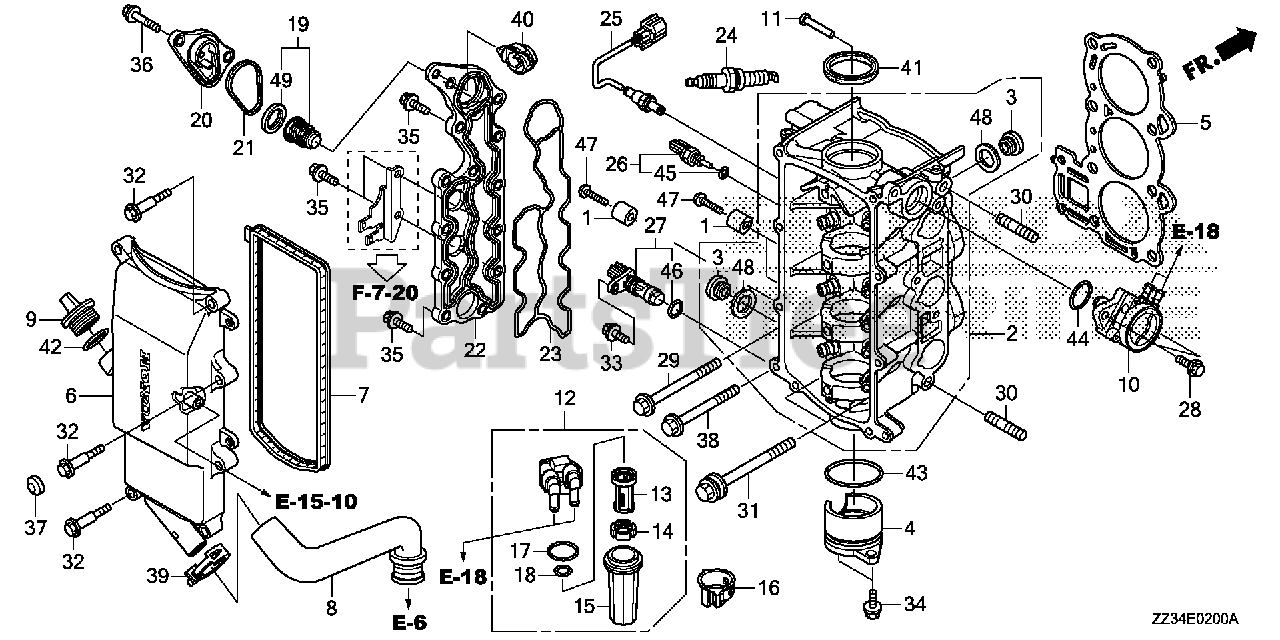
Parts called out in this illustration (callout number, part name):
1	METAL, ANODE
2	CYLINDER HEAD *NH8* (DARK GRAY)
3	BOLT, SEALING (20MM)
4	COVER, CAM THRUST
5	GASKET, CYLINDER HEAD
6	COVER, CYLINDER HEAD
7	GASKET, HEAD COVER
9	CAP, OIL (YELLOW)
10	PUMP ASSY., FUEL (MSDS)
11	LIFTER, FUEL PUMP
12	FILTER ASSY., FUEL
16	SUSPENSION, STRAINER
19	THERMOSTAT ASSY.
20	COVER, THERMOSTAT
21	O-RING, THERMOSTAT COVER
22	COVER, WATER JACKET
23	GASKET, EX. WATER JACKET COVER
24	SPARK PLUG (LMAR6C-9)
25	SENSOR, OXYGEN
26	SENSOR ASSY., WATER TEMPERATURE
27	SENSOR ASSY., TDC
28	BOLT, FLANGE (6X22)
29	BOLT, FLANGE (8X90)
30	BOLT, STUD (8X32)
31	BOLT-WASHER (9X105)
32	BOLT, HEAD COVER
33	BOLT, FLANGE (6X16)
34	BOLT, FLANGE (6X20)
35	BOLT, FLANGE (6X22)
36	BOLT, FLANGE (6X37)
37	CAP, BOLT (6MM)
38	BOLT, FLANGE (8X70)
39	CLAMP, TUBE (D29)
40	CLIP, WIRE HARNESS (25MM)
41	OIL SEAL (35X52X8)
42	O-RING (26X2.7)
43	O-RING (46.8X2.2) (NOK)
44	O-RING (31.2X2.4)
45	O-RING (9.5X1.9)
46	O-RING (15X1.9)
47	SCREW, PAN (5X20)
48	WASHER, DRAIN PLUG (20MM)
49	RUBBER, RING
